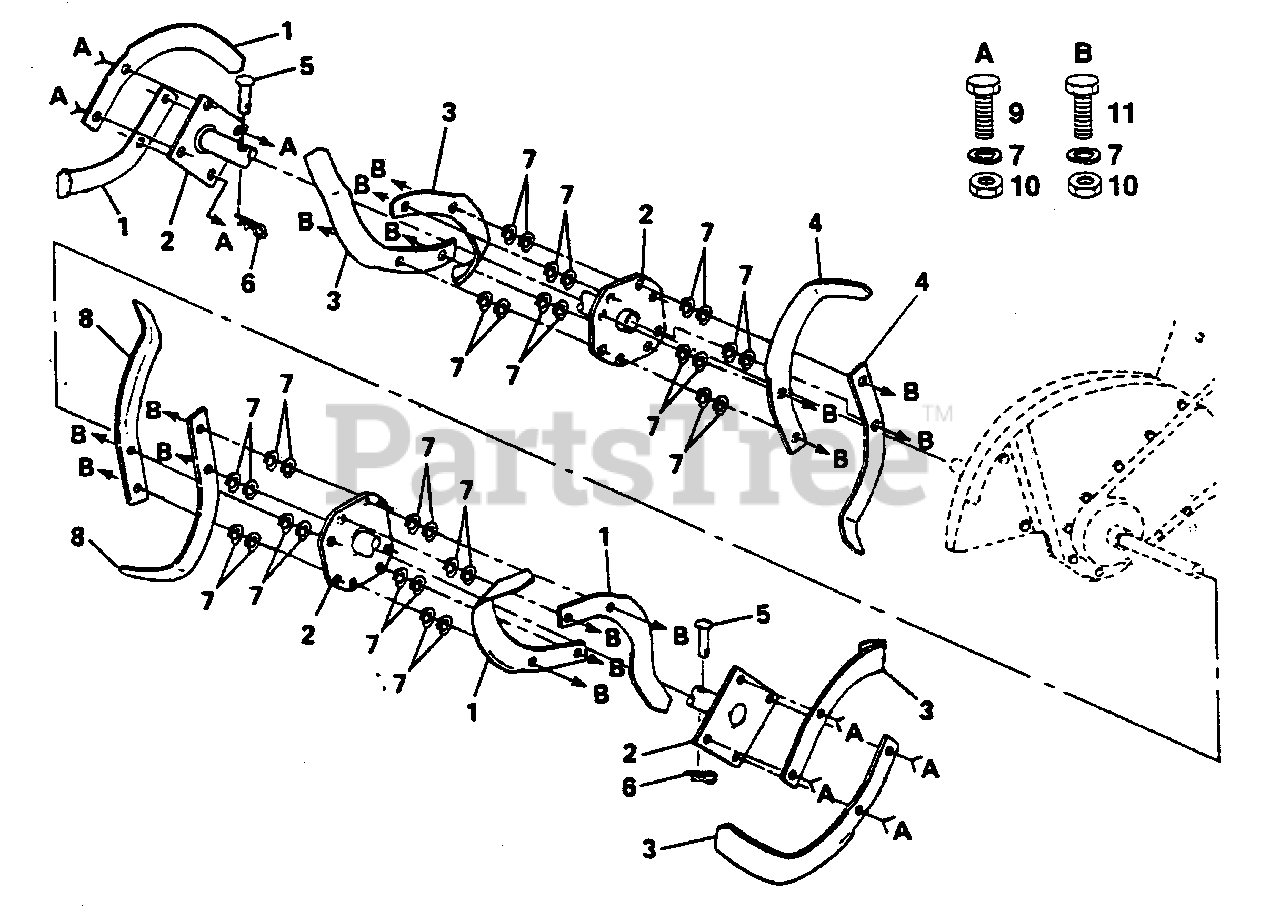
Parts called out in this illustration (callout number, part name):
1	Tine, L.H., 14" (AYP part number)
2	Hub Assembly (AYP part number)
3	Tine, R.H., 14" (AYP part number)
4	Tine, L.H., 14" (AYP part number)
5	Rivet, Panhead
6	Clip, Hairpin (AYP part number)
7	Washer, Lock 3/8 (AYP part number)
8	Tine, R.H., 14" (AYP part number)
9	Bolt, Hex Head 3/8-24 x 1 (AYP part number)
10	Nut, Hex 3/8-24 (AYP part number)
11	Bolt, Hex Head 3/8-24 x 1-1/2 (AYP part number)
